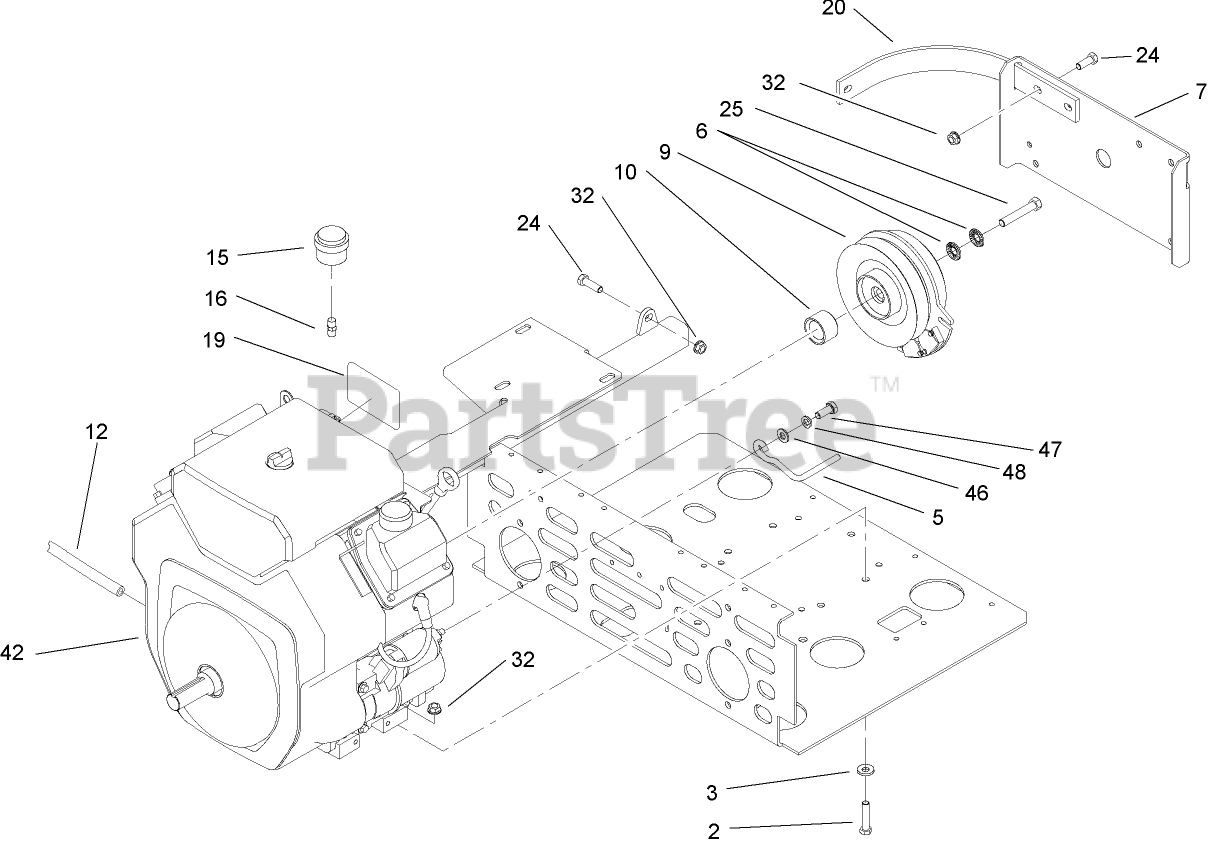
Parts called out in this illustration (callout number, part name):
2	SCREW-HH
3	WASHER-BELLEVILLE
5	ROD-BELT
6	WASHER-SPRING
7	GUARD-CLUTCH
9	CLUTCH
10	SPACER-CLUTCH
12	TUBE-DRAIN, OIL
15	INDICATOR-FILTER, AIR
16	ADAPTER-INDICATOR
20	STRAP-GUARD
24	SCREW-HH
25	SCREW-HH
32	NUT-HHF, WHIZ
46	WASHER-FLAT
47	SCREW-HH
48	WASHER-BELLEVILLE
